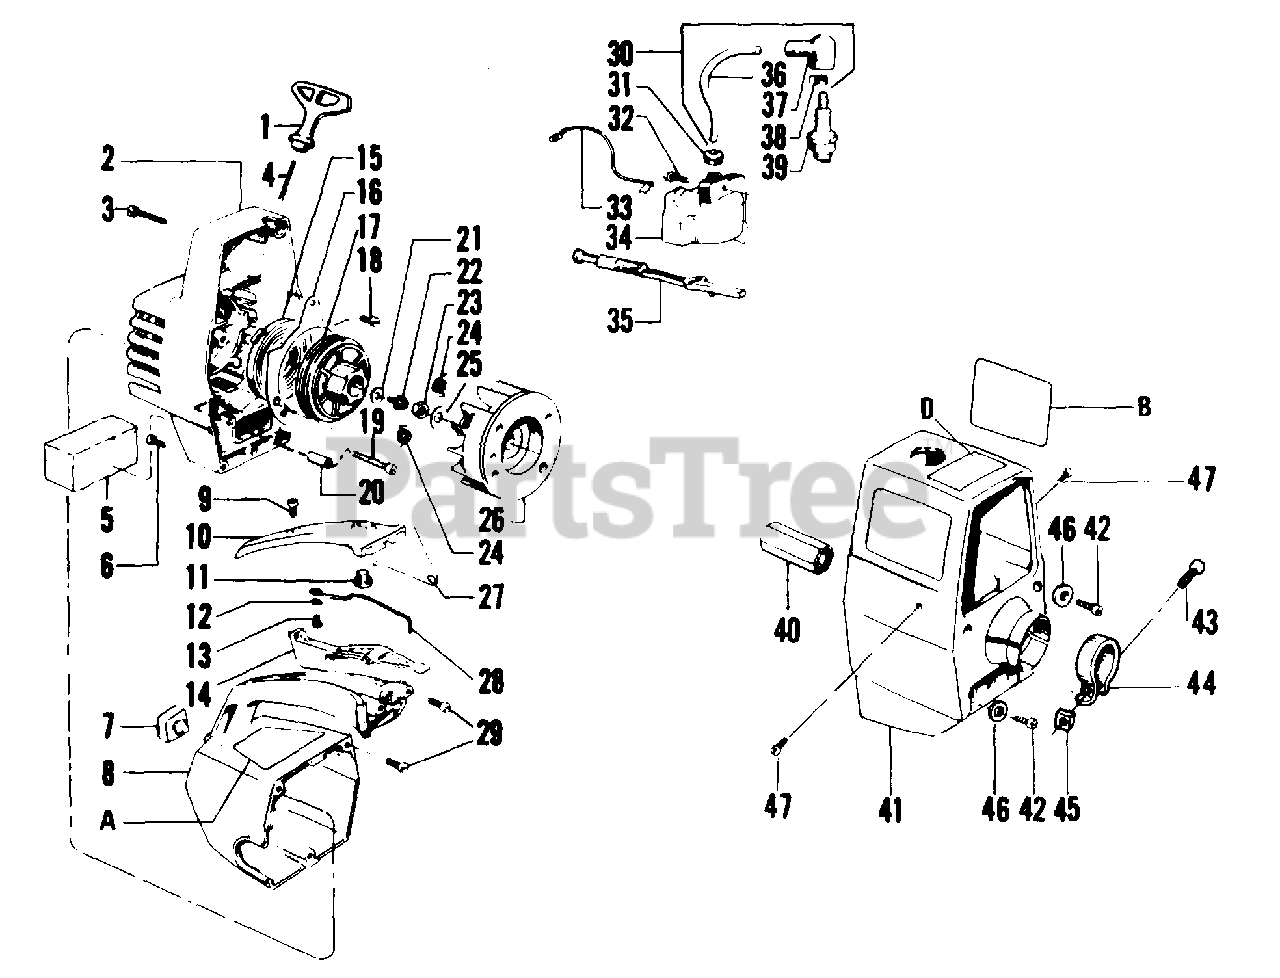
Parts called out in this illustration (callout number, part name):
1	Starter - Handle
2	Fan Housing Kit
3	Screw - 10 - 24 x 1 - 1/2 - Sems Fan Housing - Top
4	Rope Kit
5	Air Filter
6	Screw - 10 - 24 x 5/8 - Sems Fan Housing Bottom
7	Bumper - Fuel Tank Housing
8	Handle & Fuel Tank Housing
9	Screw - 8 - 16 x 3/4 - Pan Hd. - Handle Cover
10	Handle Cover
11	Button - Kill Switch
12	Washer - Kill Switch
13	Screw - 8 - 16 x 3/8 - Pan Hd. - Kill Switch
14	Trigger - Throttle
15	Starter Recoil Spring
16	Air Baffle
17	Starter Pulley
18	Screw #10 x 3/8 - Pan Hd. - Air Baffle
19	Screw - 10 - 24 x 1 - 3/16 - Plastite
20	Spacer - Air Baffle
21	Washer - Starter Pulley
22	Screw - #10 x 3/4 - Hex Washer Hd. - Starter Pulley
23	Nut - Flywheel
24	Spring - Starter Dog
25	Washer - Flywheel
26	Flywheel Assembly (Incl. #24)
27	Trigger Spring
28	Spring - Kill Switch
29	Screw - 10 - 14 x 3/4 - Pan Hd. - Fan Hsg. to Handle & Fuel Tank
30	High Tension Lead Ass'y (Incl. #36, 37 & 38)
31	Grommet - Plug Wire
32	Screw - 8 - 32 x 3/4 - Fil. Hd. - Ignition Module
33	Lead Wire - Switch
34	Kit Module
35	Knob- Choke
36	High Tension Lead Wire
37	Boot - Spark Plug
38	Connector - Sprak Plug Lead
39	Spark Plug
40	Drive Adaptor
42	Screw - 10 - 24 x 7/8 - Fil. Hd. - Shroud
43	Bolt - Clamp - 1/4 - 20 x 9/16
45	Nut - 1/4 - 20
46	Washer - Shroud
47	Screw - 10 - 24 x 5/8 Bind. Hd.
